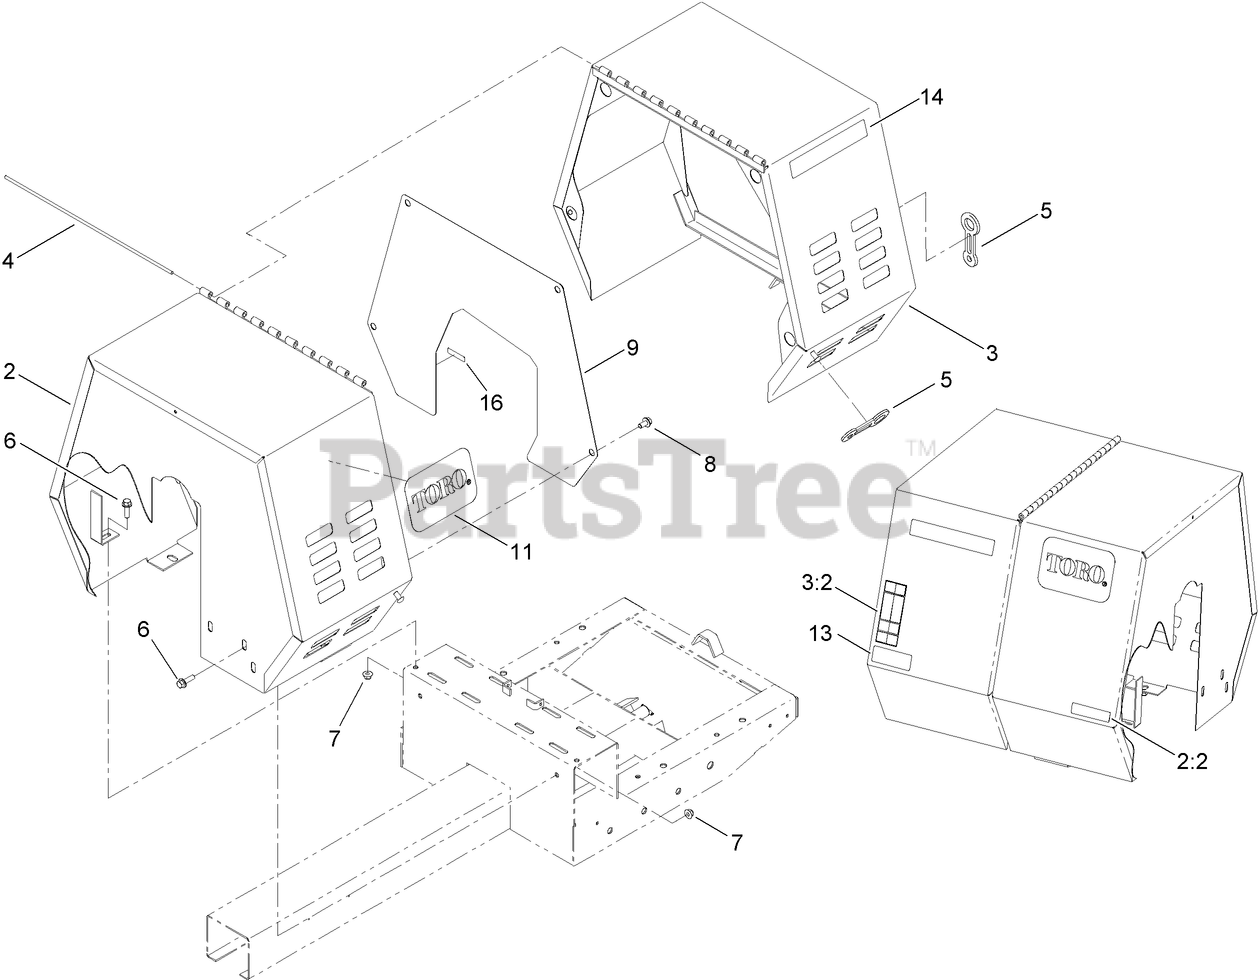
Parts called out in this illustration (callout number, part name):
2	STATIONARY COWL ASM
2:2	DECAL-ARRESTER, SPARK
3	MOVABLE COWL ASM
3:2	DECAL-WARNING
5	LATCH-RUBBER
6	SCREW-HHF
7	NUT-HF, NI
8	SCREW-HWH
9	PLATE-GUARD, BELT
11	DECAL
14	DECAL-MM-850E
16	DECAL-GREASE
